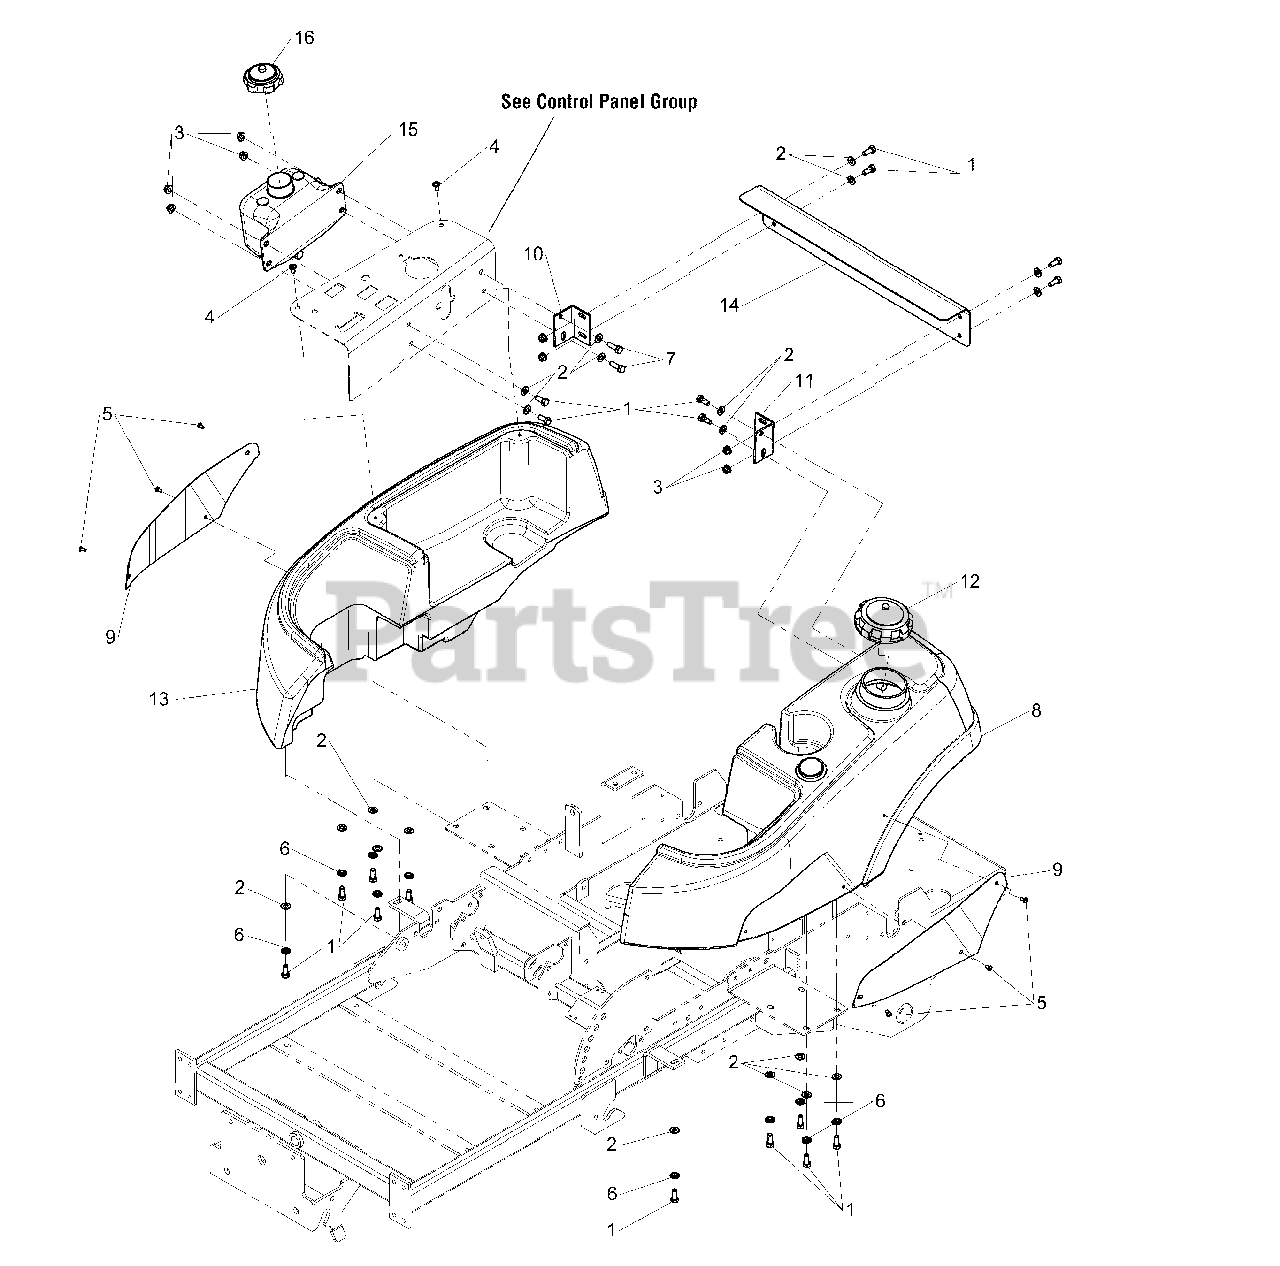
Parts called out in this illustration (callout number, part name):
1	BOLT, 5/16-18 X 3/4" GRD5
2	WASHER, 5/16" SAE
3	NUT, 5/16-18 HEX NYLOCK FLANGE
4	SCREW, ALLEN HEAD, 1/4-20X1/2
5	SCREW, Allen Head, #10-24 x 3/8"
6	WASHER, 5/16" LOCK
7	BOLT, 5/16-18 X 1" GD5
8	ASSM,
9	PLATE, FUEL TANK BADGE
10	BRACKET, REAR SUPPORT - RH
11	BRACKET, REAR SUPPORT - LH
12	CAP, FUEL TANK, 3-1/2" NECK
13	TANK, FUEL - RH
14	PLATE, SUPPORT, REAR TANK
15	TANK, 2QT HYDRAULIC
16	CAP, HYDRAULIC RESERVOIR
17	ELBOW FITTING
19	HOSE, 20"
20	HOSE CLAMP
21	SCREEN FITTING
